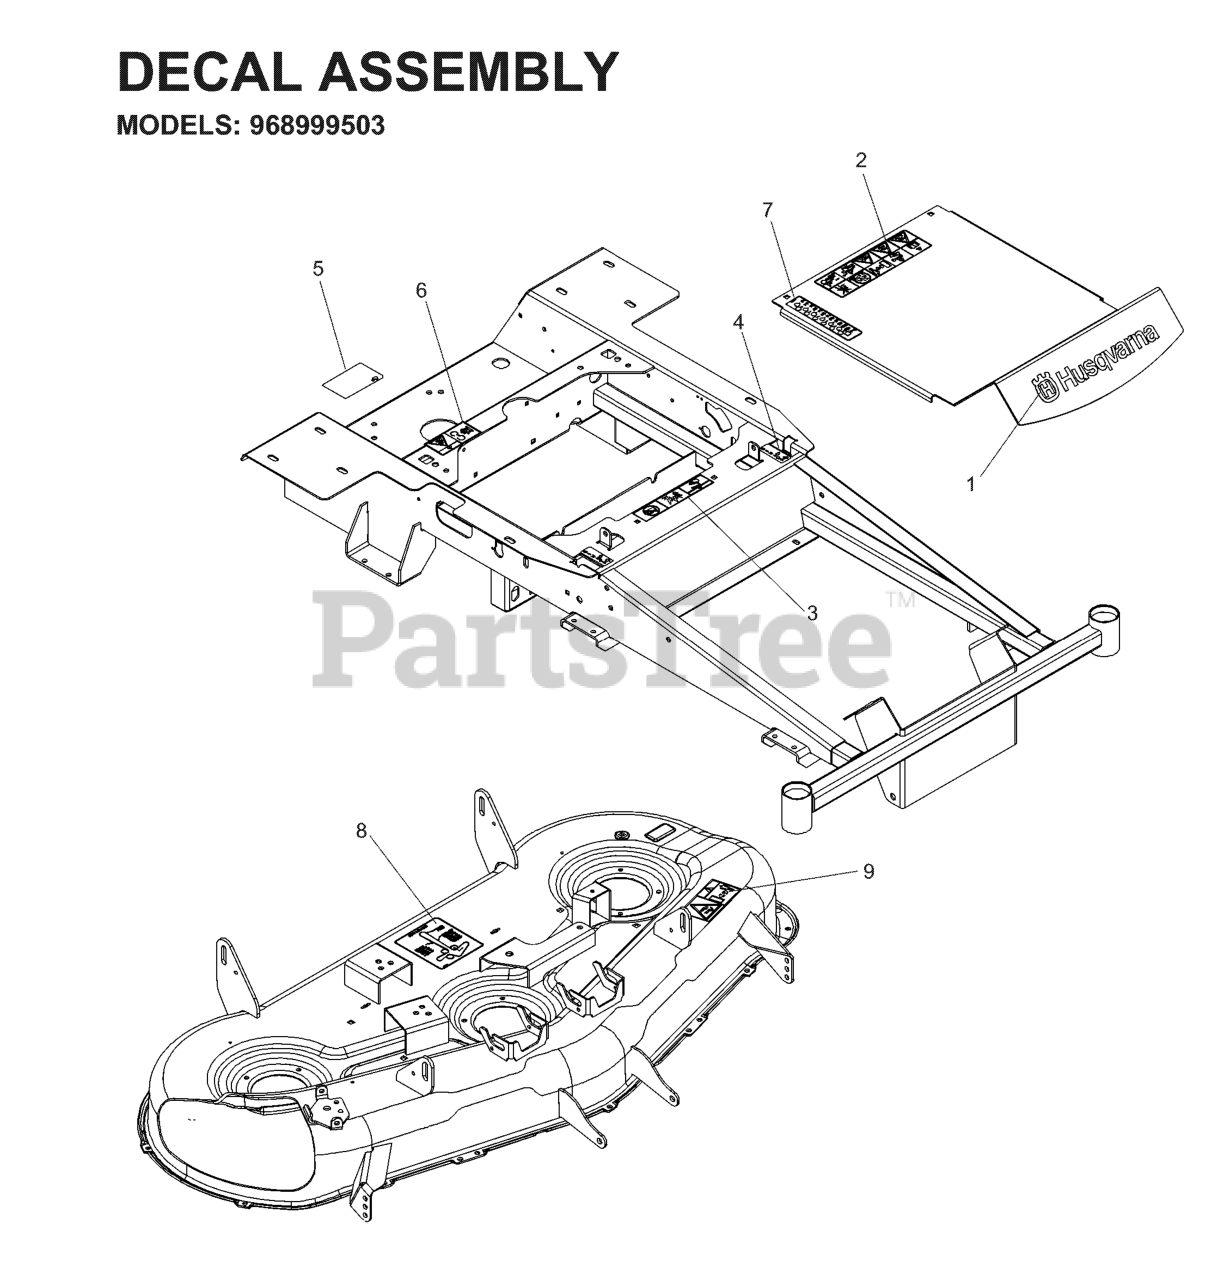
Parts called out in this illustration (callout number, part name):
1	DECAL, HUSQ 12" BLUE
2	DECAL, WARNING
3	EURO DECAL-BATTERY WARNIN6
4	DECAL, MOTION CONTROL
5	DECAL, DO NOT TOW
6	DECAL, BELT DRIVE
7	DECAL, HEIGHT, EZ
8	DECAL, BELT ROUTING
9	DECAL, EURO SEVERING
